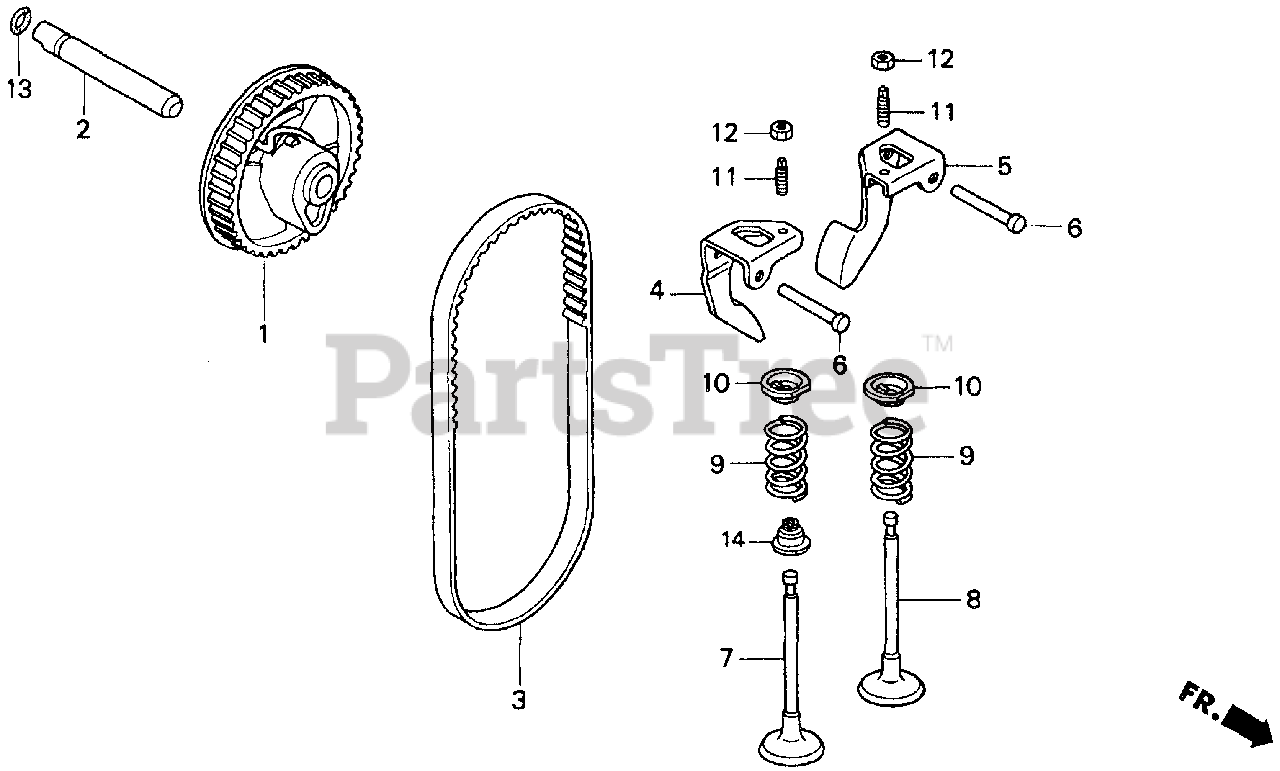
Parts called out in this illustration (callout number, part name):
1	PULLEY, CAMSHAFT
2	SHAFT, CAM PULLEY
3	BELT, TIMING (79HU7 G-200)
4	ARM, IN. VALVE ROCKER
5	ARM, EX. VALVE ROCKER
6	SHAFT, ROCKER ARM
7	VALVE, IN.
8	VALVE, EX.
9	SPRING, VALVE
10	RETAINER, IN. VALVE SPRING
11	SCREW, TAPPET ADJ.
12	NUT, TAPPET ADJ.
13	O-RING (6.8X1.9)
14	SEAL, VALVE STEM
